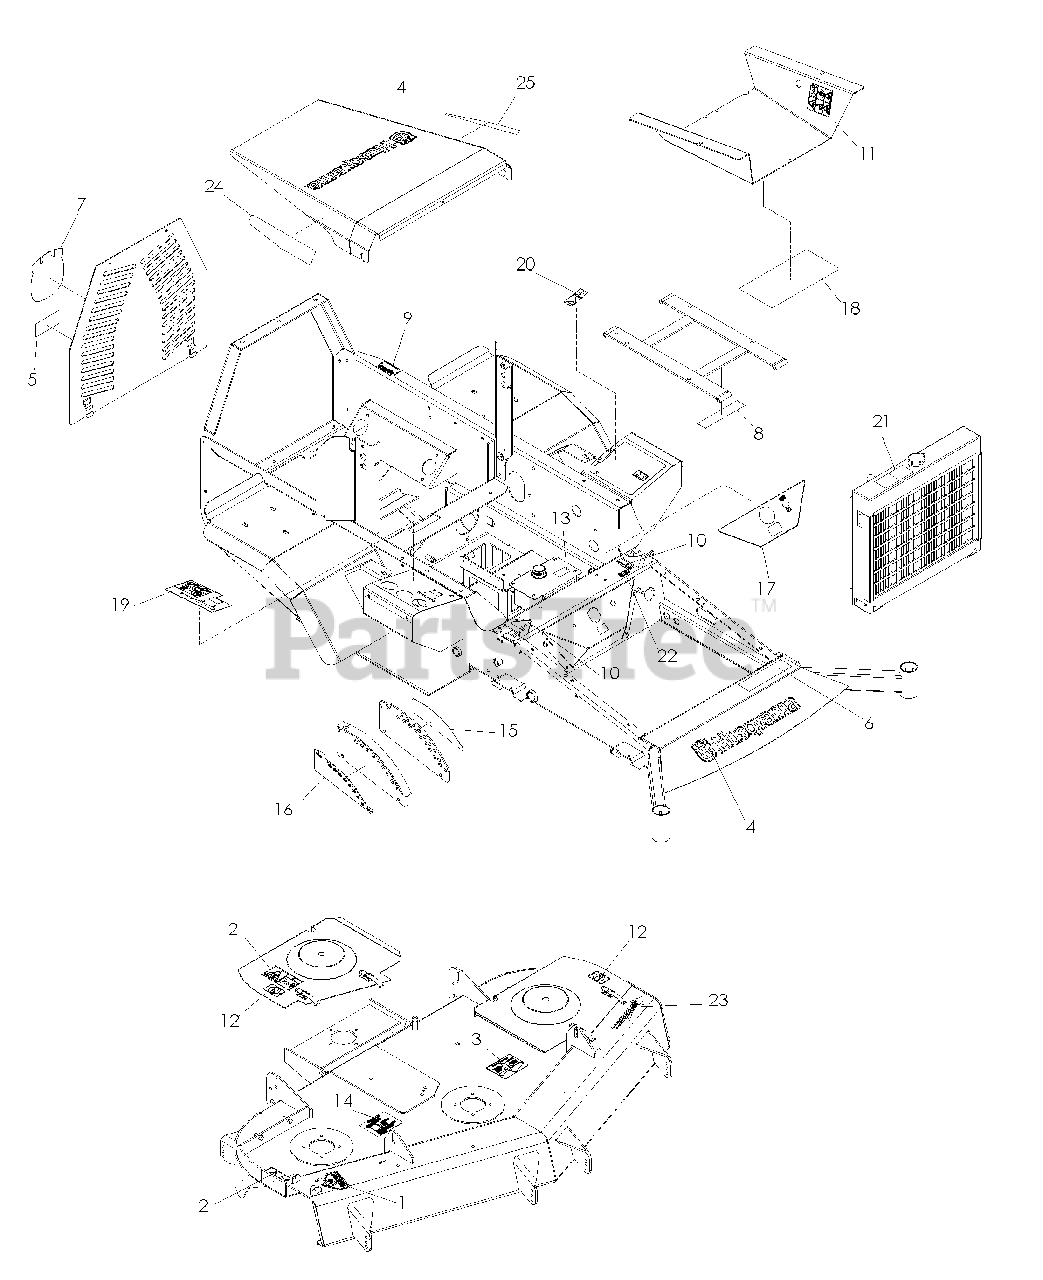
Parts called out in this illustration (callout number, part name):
1	DECAL, CPSC
2	DECAL, SEVERING
3	DECAL, BELT ROUTING
4	DECAL, HUSQVARNA
5	DECAL, BELT DRIVES
6	DECAL, BZ6127
6	DECAL, BZ7234
7	DECAL, CROWN
8	DECAL, BATTERY WARNING
9	DECAL, PROP 65
10	DECAL, MOTION CONTROL
11	DECAL, WARNING
12	DECAL, NO STEP
13	DECAL, OIL TANK
14	DECAL, ANTI-SCALP
15	DECAL, HEIGHT
16	DECAL, HEIGHT
17	DECAL, CONSOLE
18	DECAL, SERVICE
19	DECAL, RT CONSOLE
20	DECAL, 12V DC
21	DECAL, HOT
22	DECAL, FAST/SLOW/TRACK
23	DECAL, TUNNELRAM 8"
24	DECAL, 34 TURBO, RT
24	DECAL, 27 DIESEL, RT
25	DECAL, 34 TURBO, LT
25	DECAL, 27 DIESEL, LT
